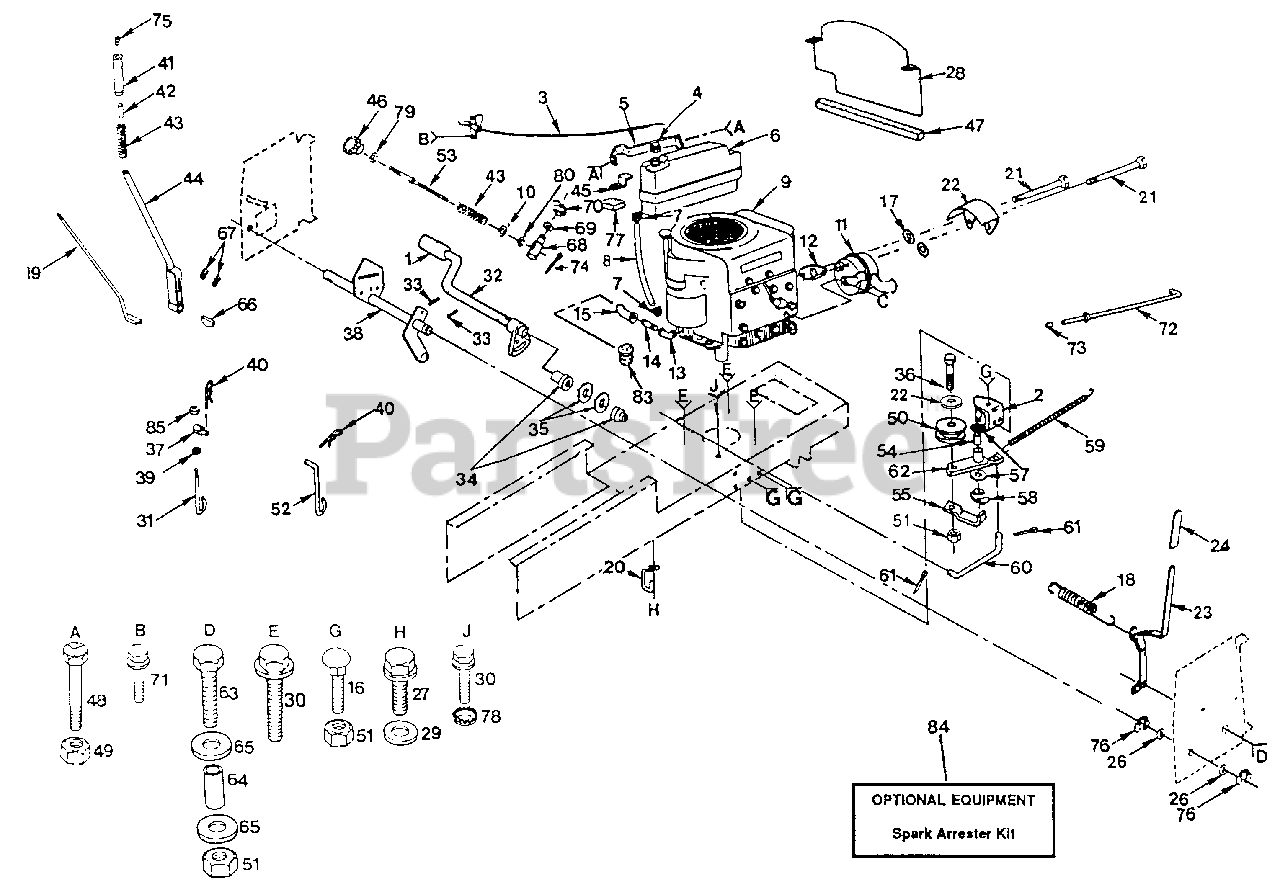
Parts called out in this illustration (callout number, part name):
1	Pedal Cover
2	Bracket Assembly, Clutch
3	Control, Throttle
4	Fuel Cap
5	Support, Tank, Fuel
6	Tank, Fuel
7	Hose Clamp
8	Fuel Line
9	Engine Briggs & Stratton, Type No. 0412-01
10	Washer 13/32 x 5/8 x 16 Ga.
12	Gasket, Exhaust
13	450 Street Elbow 3/8 NPT
14	Std. Pipe Nipple 3/8-18 NPT x 3 1/2
15	900 Elbow 3/8 NPT
16	Bolt, Carriage 3/8-16 x 3/4
17	Washer Lock 15/32 x 11/16 x 16 Ga.
18	Spring, Extension
19	Rod Assembly, Lever
20	Retainer, Belt, Chassis L.H.
21	Bolt 5/16-18 x 5/8
22	Shield, Heat, Muffler
23	Handle, Clutch Attachment
24	Grip, Handle
25	Washer 13/32 x 13/16 x 16 Ga.
26	Washer 29/32 x 1-1/4 x 16 Ga.
27	Screw, Hex Washer Thrd. Rolling 3/8-16 x 3/4
28	Baffle, Vertical
29	Washer 13/32 x 13/16 x 12 Ga.
30	Screw, Hex Washer Hd. Thread Rolling 3/8-16 x 1-1/4 Type TT
31	Link, Lift, Adjustable
32	Shaft, Pedal, Foot
33	Roll Pin 3/16 x 1
34	Bearing, Nylon
35	Washer, 21/32 x 1 x 16 Ga.
36	Bolt, Fin Hex 3/8-16 x 2-3/4
37	Trunnion, Lift
38	Shaft, Assembly Lift
39	Nut, Hex Jam 7/16-20
40	Retainer Spring
41	Grip, Handle
42	Plunger, Lever, Hand
43	Spring
44	Lever Assembly, Hand Kit
45	Brace, Tank
46	Handle, Adjust Lift
47	Strip, Foam 14.5"
48	Bolt, Hex 5/16-18 x 3/4 Gr. 5
49	Locknut 5/16-18 Gr. B
50	Pulley, Idler
51	Nut, Crownlock 3/8-16
52	Link, Lift
53	Rod, Adjust, Lift
55	Retainer, Belt
57	Washer, Hardened
58	Ring, Klip
59	Spring, Return Clutch
60	Link, Clutch
61	Pin, Cotter 1/8 x 3/4
62	Arm, Asm. Idler
63	Bolt Hex 3/8-16 x 1-1/2
64	Bushing, Handle, Clutch
65	Washer 3/8 x 1 x 12 Ga.
66	Woodruff Key 1/4 x 1
67	Set Screw, Hex Socket Forged Headless 3/8-16 x 3/8
68	Trunnion, Stop, Depth
69	Washer 15/32 x 3/4 x 16 Ga.
71	Screw Hex Thread Cutting 1/4-20 x 5/8
72	Rod, Brake, Park
73	Plunger Cap
74	Cotter Pin 3/32 x 1/2
75	Button, Plunger
77	Pad, Spacer
78	Washer, Lock 3/8-Ext. Tooth
79	Nut, Hex Jam 3/8-16
80	Nut, Special
83	Oil Drain Plug
84	Spark Arrester Kit
85	Nut, Jam Crownlock 7/16-20
